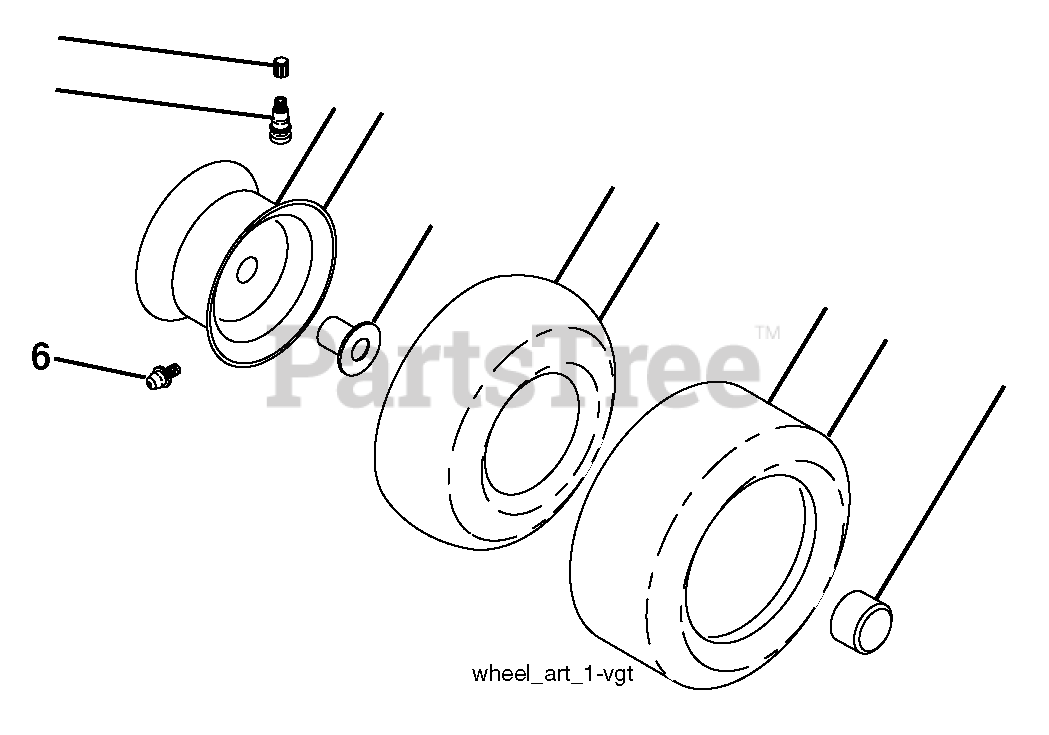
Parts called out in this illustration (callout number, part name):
1	Cap, Valve, Tire
2	Stem, Valve
3	Rim Assembly, Front
4	Tube, Front
5	Tire, Front
6	Fitting, Grease
7	Bearing, Flange
8	Cap, Axle
9	Tire, Rear
10	Tube, Rear
11	Rim Assembly, Rear
11	Sealant, Tire (10 oz. Tube)
